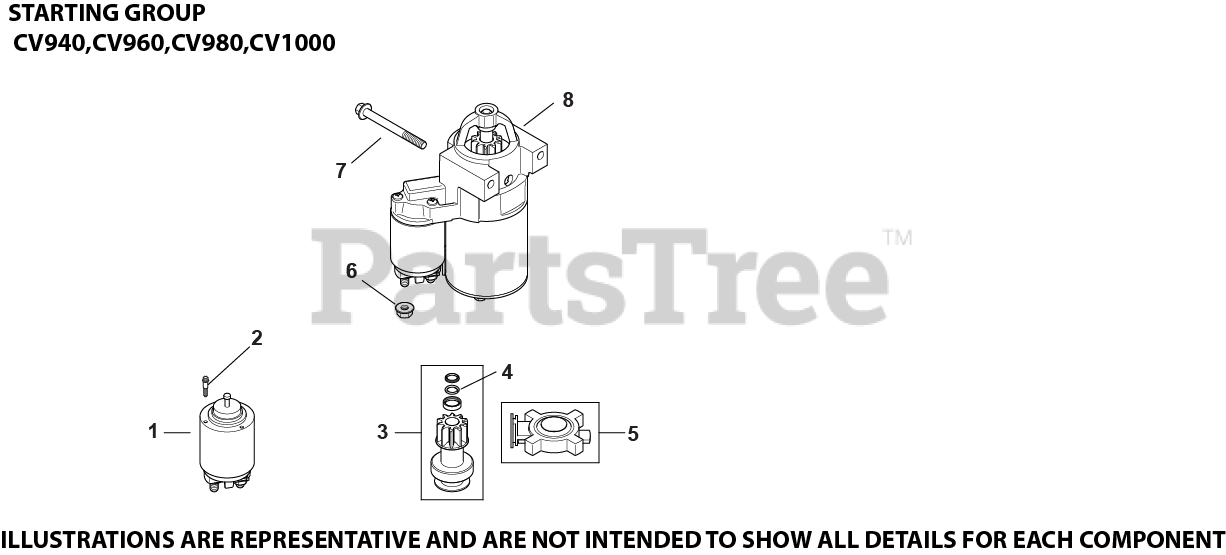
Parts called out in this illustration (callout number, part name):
1	KIT, SOLENOID
2	SCREW, EXTERNAL TORX HEAD
3	KIT, STARTER PINION
4	RING, RETAINING
5	KIT, BRUSH HOLDER
6	NUT, FLG M8X1.25
7	SCREW, FLG M8X1.25X80
8	ELECTRIC STARTER - SOLENOID SHIFT USE 25 098 20-s
